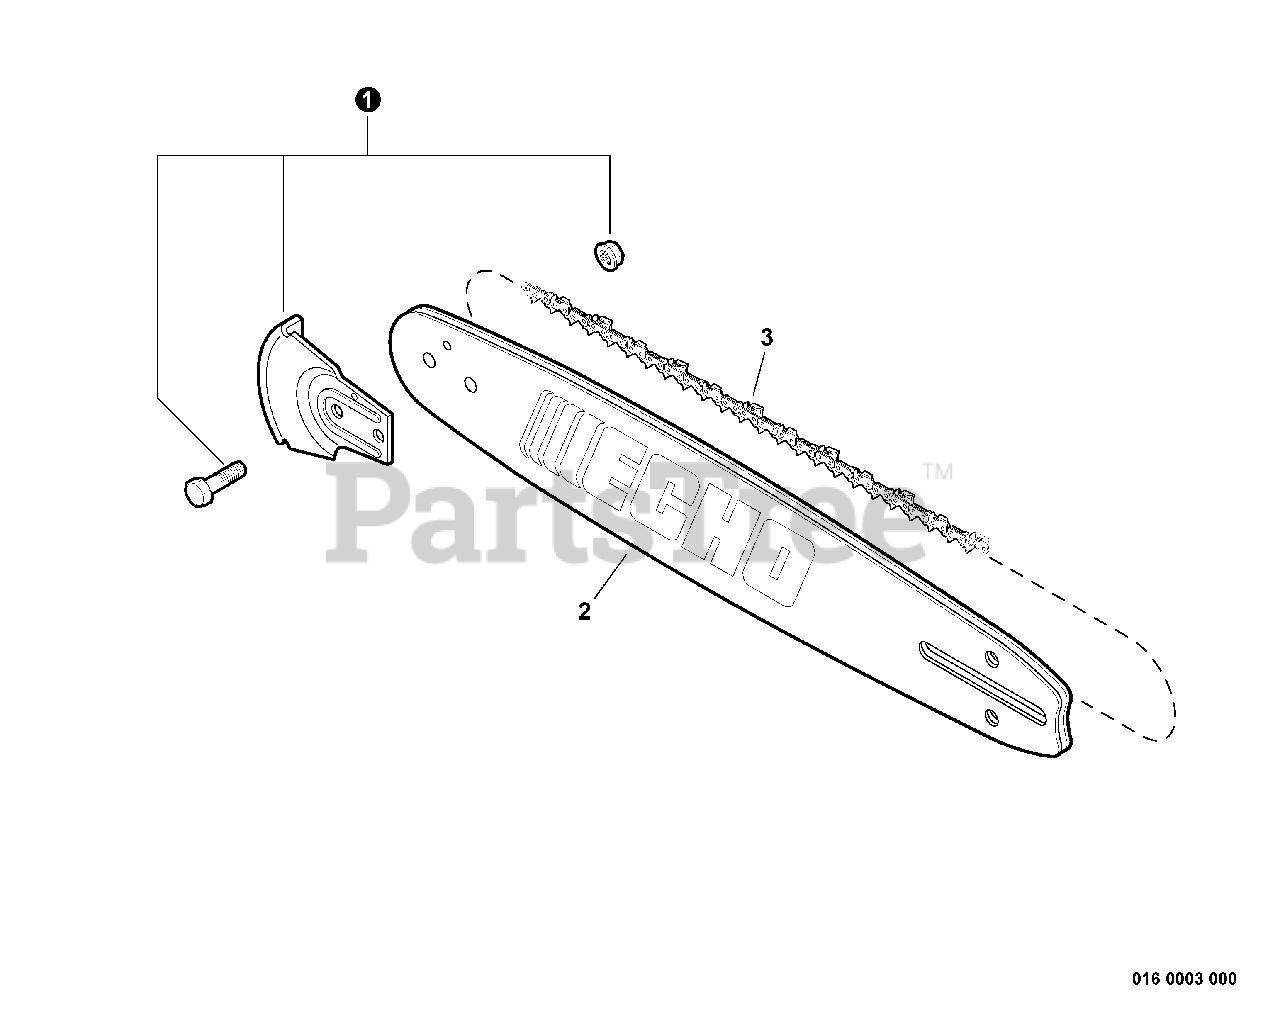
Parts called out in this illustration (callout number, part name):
1	KICK GUARD KIT
2	GUIDE BAR - 12" (30cm)
2	GUIDE BAR - 14" (35cm)
2	GUIDE BAR - 16" (40cm)
2	GUIDE BAR - 12" (30cm) Intenz
2	GUIDE BAR - 14" (35cm) Intenz
2	GUIDE BAR - 16" (40cm) Intenz
3	SAW CHAIN - 12" (30cm)
3	SAW CHAIN - 14" (35cm)
3	SAW CHAIN - 16" (40cm)
